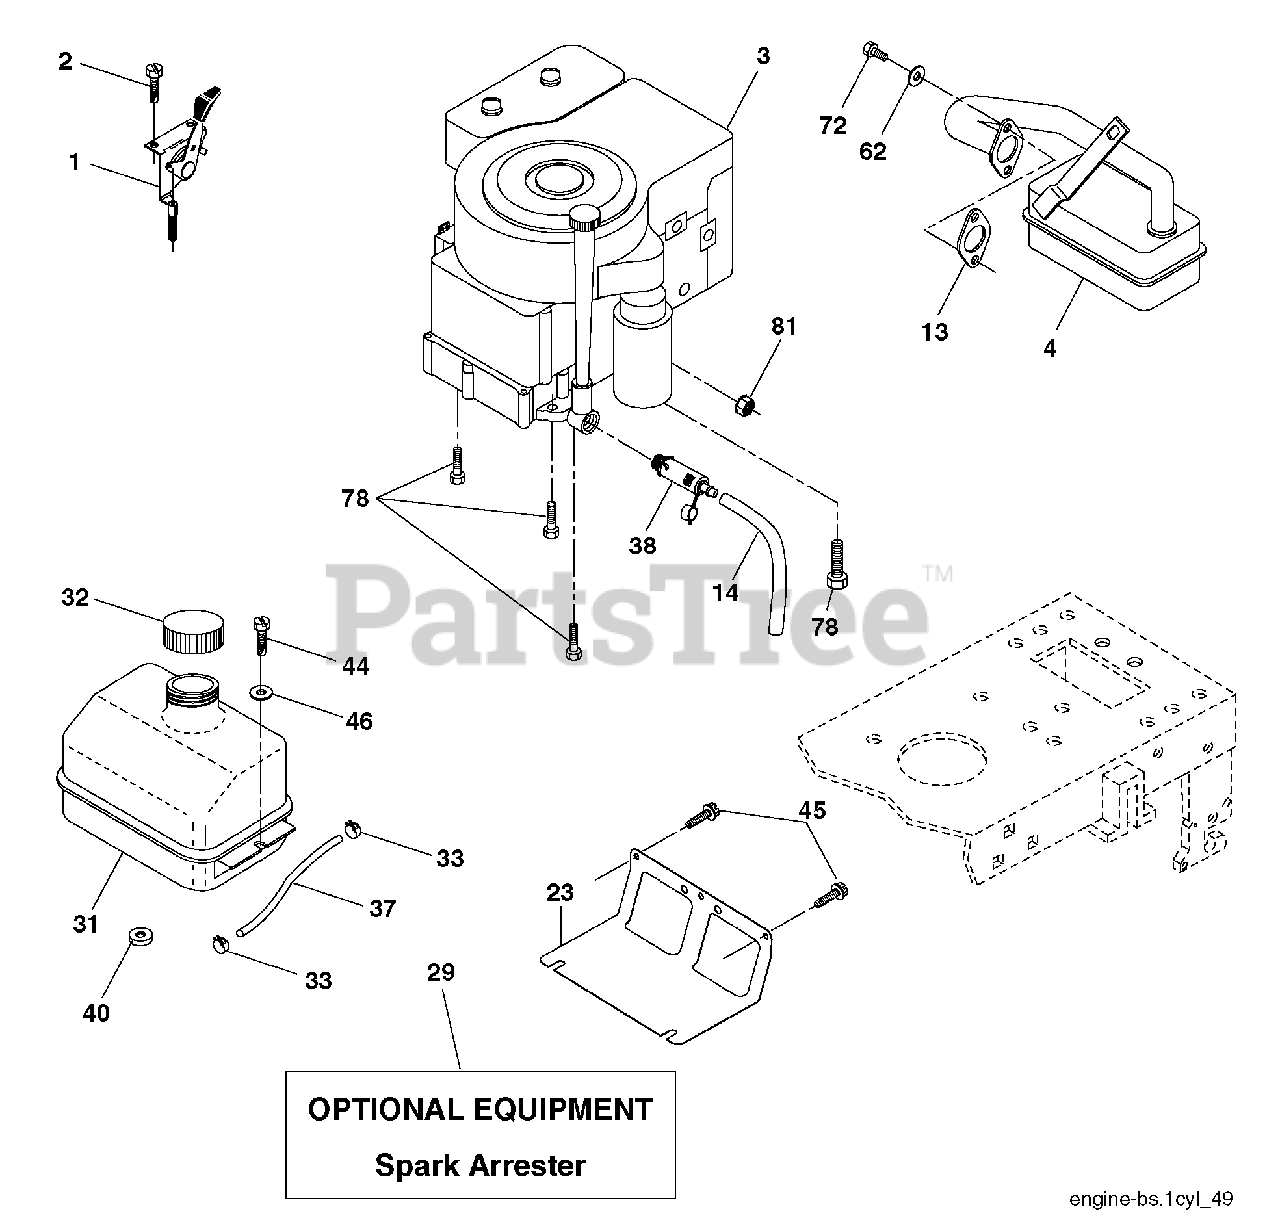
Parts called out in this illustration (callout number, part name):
1	Control Throttle /Choke Flag
2	Screw Hex Thd Cut 1/4-20 x 1/2
4	Muffler Exhaust B&S Lt
13	Gasket 1 313 Id Tin Plated
14	Tube Drain Oileasy
23	Shield Browning/Debris Guard
29	Arrestor Spark
31	Tank Fuel 1 25 Fr
32	Cap Asm Fuel Top
33	Clamp Hose Blk
37	Line Fuel 20”
38	Plug Drain Oileasy
40	Bushing Snap Nyl Blk Fuel Line
44	Screw Hexwsh Thdrol 1/4-20 x 3/4
45	Screw Hex Wsh Thdrol 3/8-16
46	Washer 9/32 X 7/8 X 16 Ga.
62	Washer Split
72	Screw Socket Head 5/16-18 x .75
78	Screw Thdrol 3/8-16 x 1-1/4
81	Nut Keps Hex 1/4-20 unc
